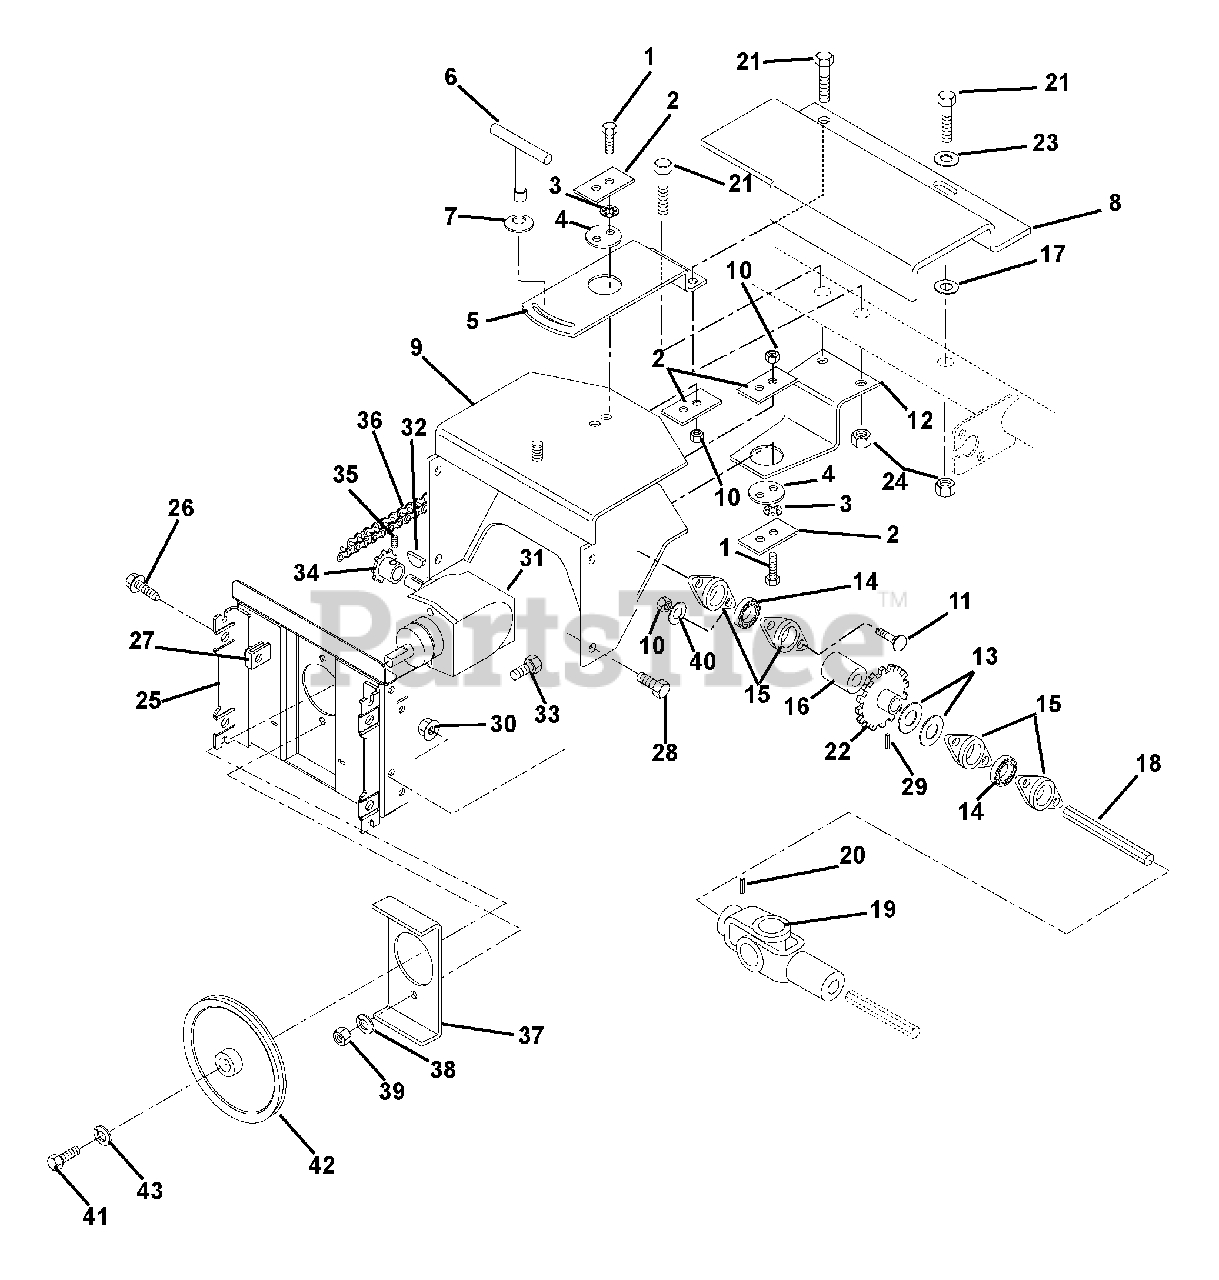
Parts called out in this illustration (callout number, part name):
1	@BLT-HEX .31-18X1.25 GR5 YWZC
2	RETAINER
3	@WSHR-LK-EXT.326X.599X.031YWZC
4	PIVOT CENTER
5	PLATE, TOP MOUNT
6	T-LOCK HANDLE
7	WSHR-BLVL .63X1.625X.14
8	GUARD, SHAFT
9	FRAME, ADAPTOR
10	@NUT-LK-CTR .31-18 YWZC
11	@BLT-RDHDSQNK .31-18X.75 G5YZ
12	PLATE, BOTTOM MOUNT
13	WSHR-FL-STL 1.015X1.500X.125
14	BRG-BALL .884HEXX52MMX1.07
15	BEARING FLANGE
16	SPACER 1.006X1.307X.500
17	WSHR-FL-STL .390X.88X.18 YWZC
19	JOINT, UNIVERSAL
20	PIN-ROLL .188X1.50
21	@BLT-HEX .38-16X3.25 GR5 YWZC
22	SPROCKET
23	@WSHR-FL-STL.406X.812X.065 YWZ
24	@NUT-LK-CTR .38-16 YWZC
25	PLATE, MOUNTING-BROOM
26	BLT-SERHFWH .38-16X.75 YWZC
27	NUT-RTNR .375-16X.37
28	@BLT-HEX .38-16X.75 GR5 YWZC
29	PIN-ROLL .188X1.75
30	@NUT-LK-CTR .38-16 YWZC
31	GEAR BOX ASSEMBLY
32	KEY-WDRF .188X.75X.313 SAE 9
33	@BLT-HEX .38-16X1.25 GR5 YWZC
34	SPROCKET
35	SCR-SET .25-20X.38 SKHCUPNL OH
36	ROLLER CHAIN #41 - 34 PITCHES
37	PLATE, STIFFENER
38	@WSHR-LK .38X.094 REG YWZC
39	@NUT-HEX .38-16 YWZC
40	@WSHR-FL-STL.38X.875X.083 YWZC
41	BLT-HEX .31-24X.75 YWZC GR5
42	PULLEY, 4L W/HUB, .87 X 8.5
43	WSHR-LK .312X.097 HVY YWZC
